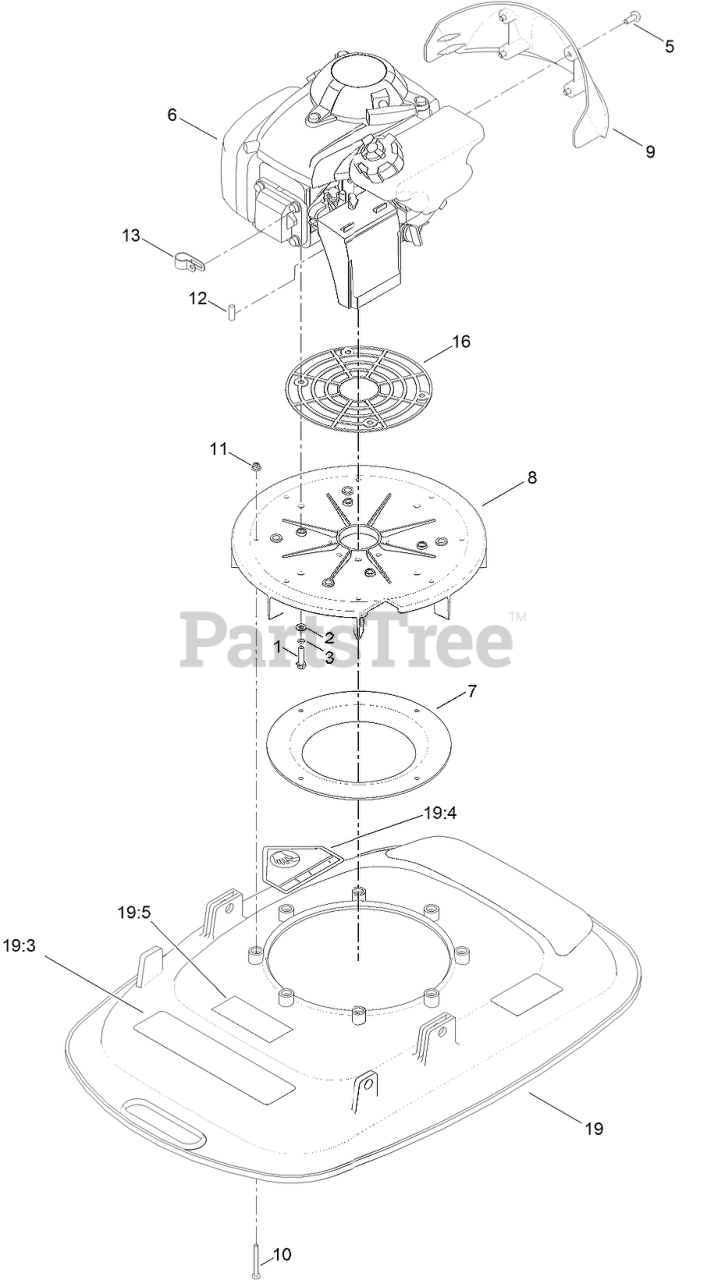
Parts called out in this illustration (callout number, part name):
1	SCREW-HH
2	WASHER-PLAIN
3	WASHER-SPRING
5	SCREW-SOC, HD
6	ENGINE-HONDA
7	BELL-MOUTH
8	PLATE-ENGINE
9	COVER-SUMP
10	SCREW-PPH
11	NUT-HHF, NY
12	KEY-DRIVE, SQUARE ENDED
13	CLIP-P, NATURAL
16	SINK-HEAT
19:3	DECAL-WARNING
19:4	DECAL-DANGER
